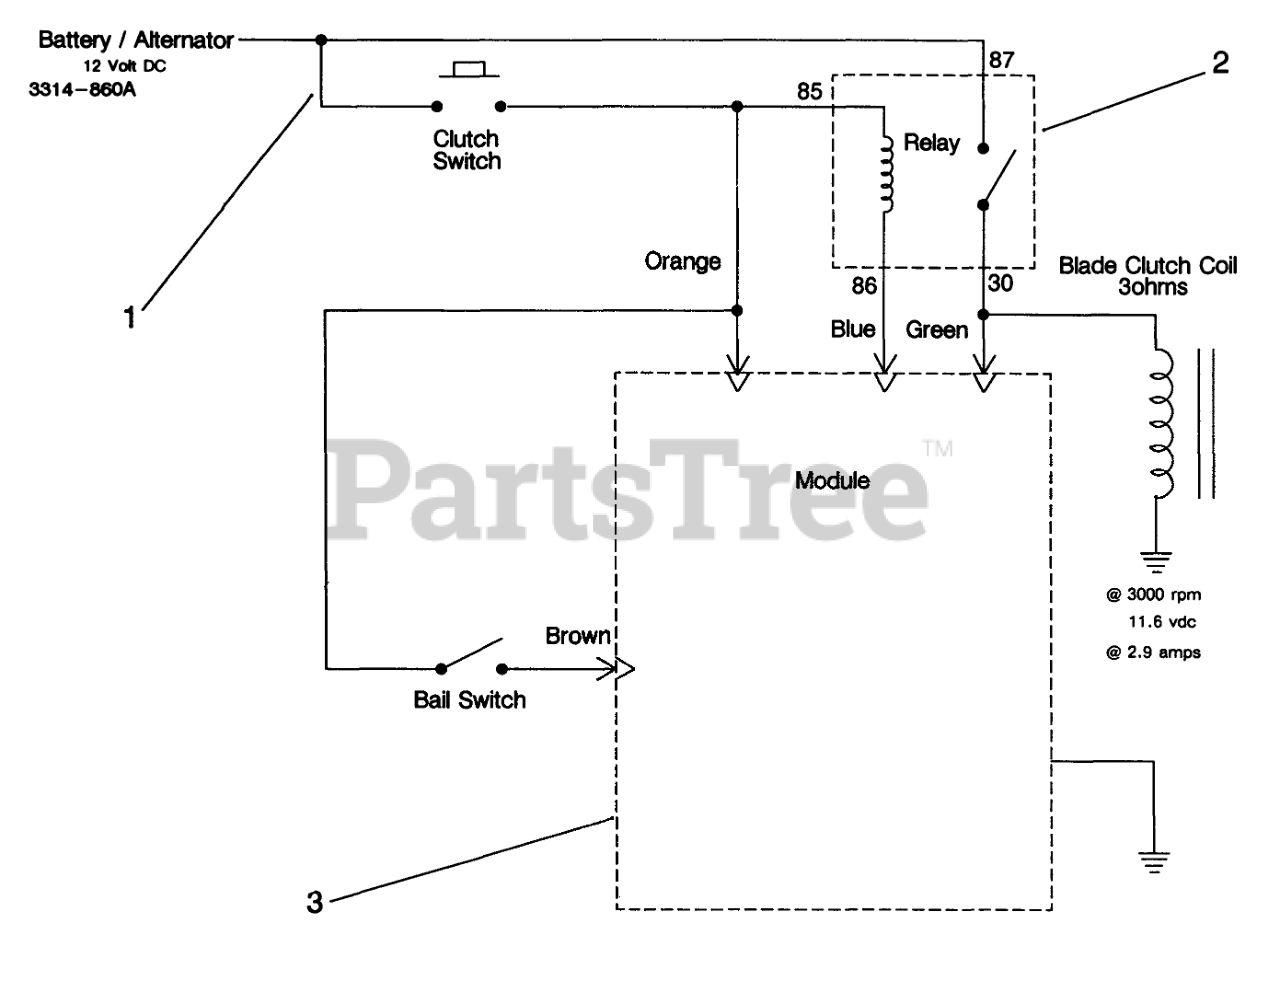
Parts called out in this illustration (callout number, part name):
1	Wire Harness
2	Module
3	RELAY
